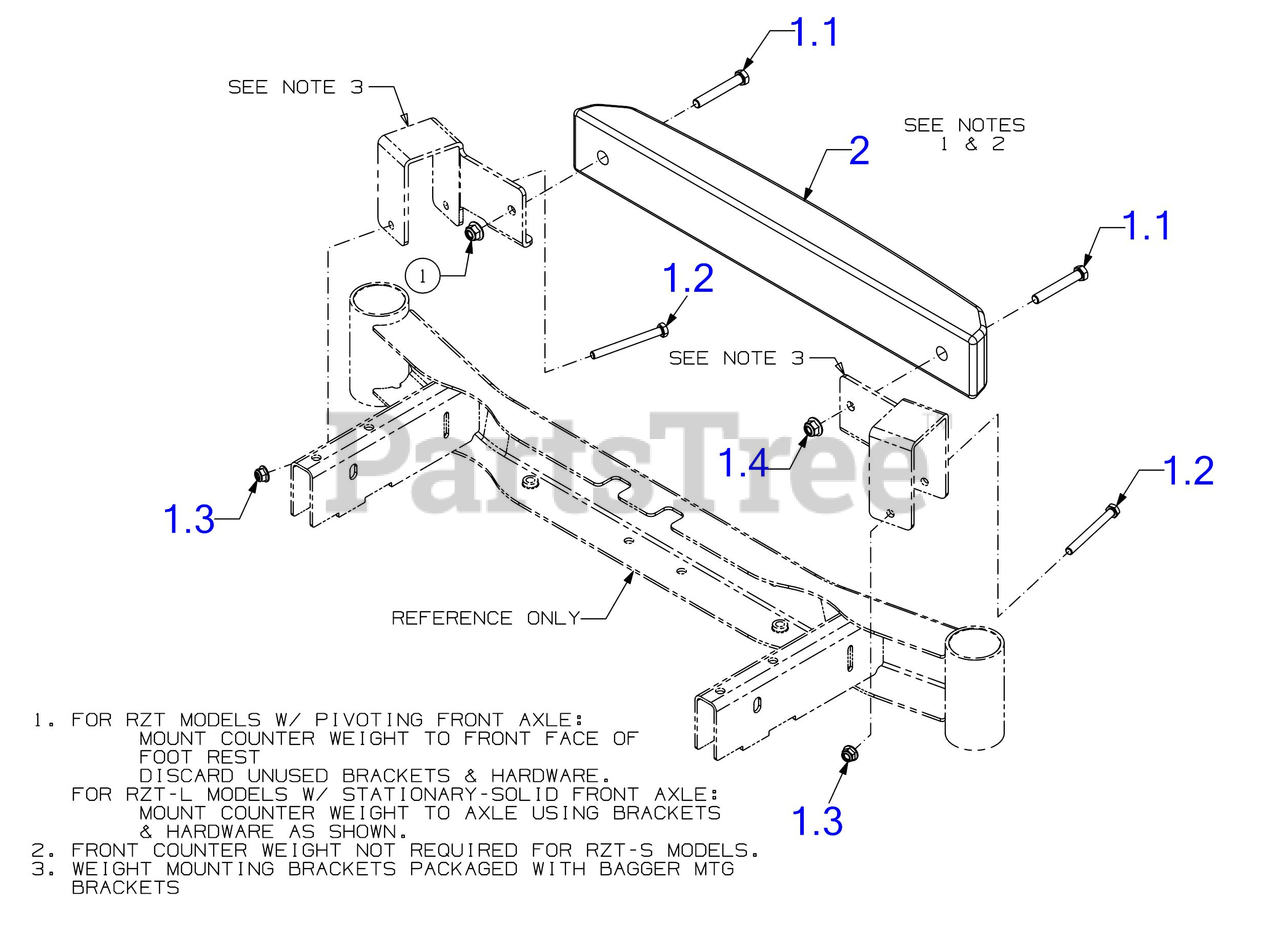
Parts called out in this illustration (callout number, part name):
1	HARDWARE PACK
1.1	HEX SCREW-3/8-16X2.5 GR5
1.2	SCREW 5/16-18 x 3.25 GR5
1.3	FLANGE LOCK NUT 5/16-18
2	BAGGER WEIGHT
